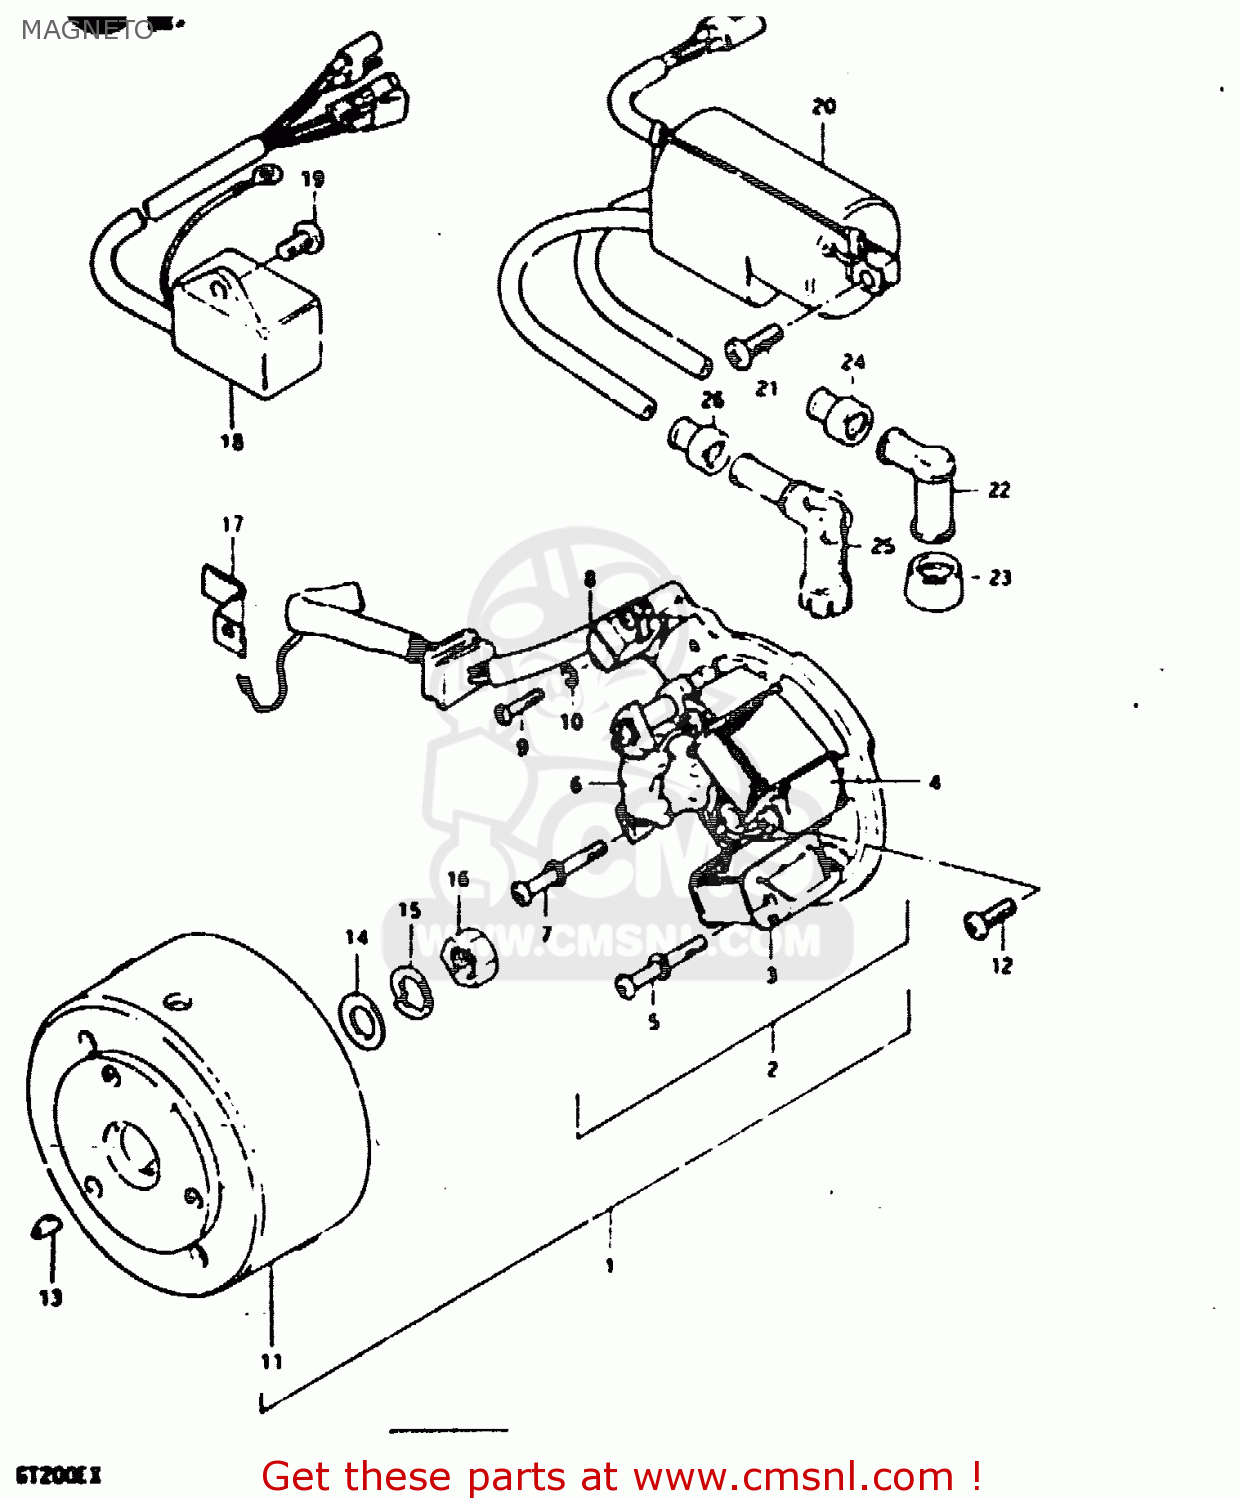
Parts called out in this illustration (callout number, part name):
1	MAGNETO ASSY
2	STATOR ASSY
3	COIL,LIGHTING(A)
4	COIL, LIGHTING B
5	SCREW
6	COIL, PRINAR,
7	SCREW
8	COIL,PULSER
9	SCREW
10	LOCK WASHER
11	ROTCH
12	SCREW
13	KEY
14	WASHER
15	WASHER,LOCK 12
16	NUT
17	CLAMP
18	C.D.I. UNIT ASSY
19	SCREW 6X12
20	COIL ASSY, IGNITION
21	SCREW
25	CAP,SPARK PLUG
26	SEAL,SPARK PLU
